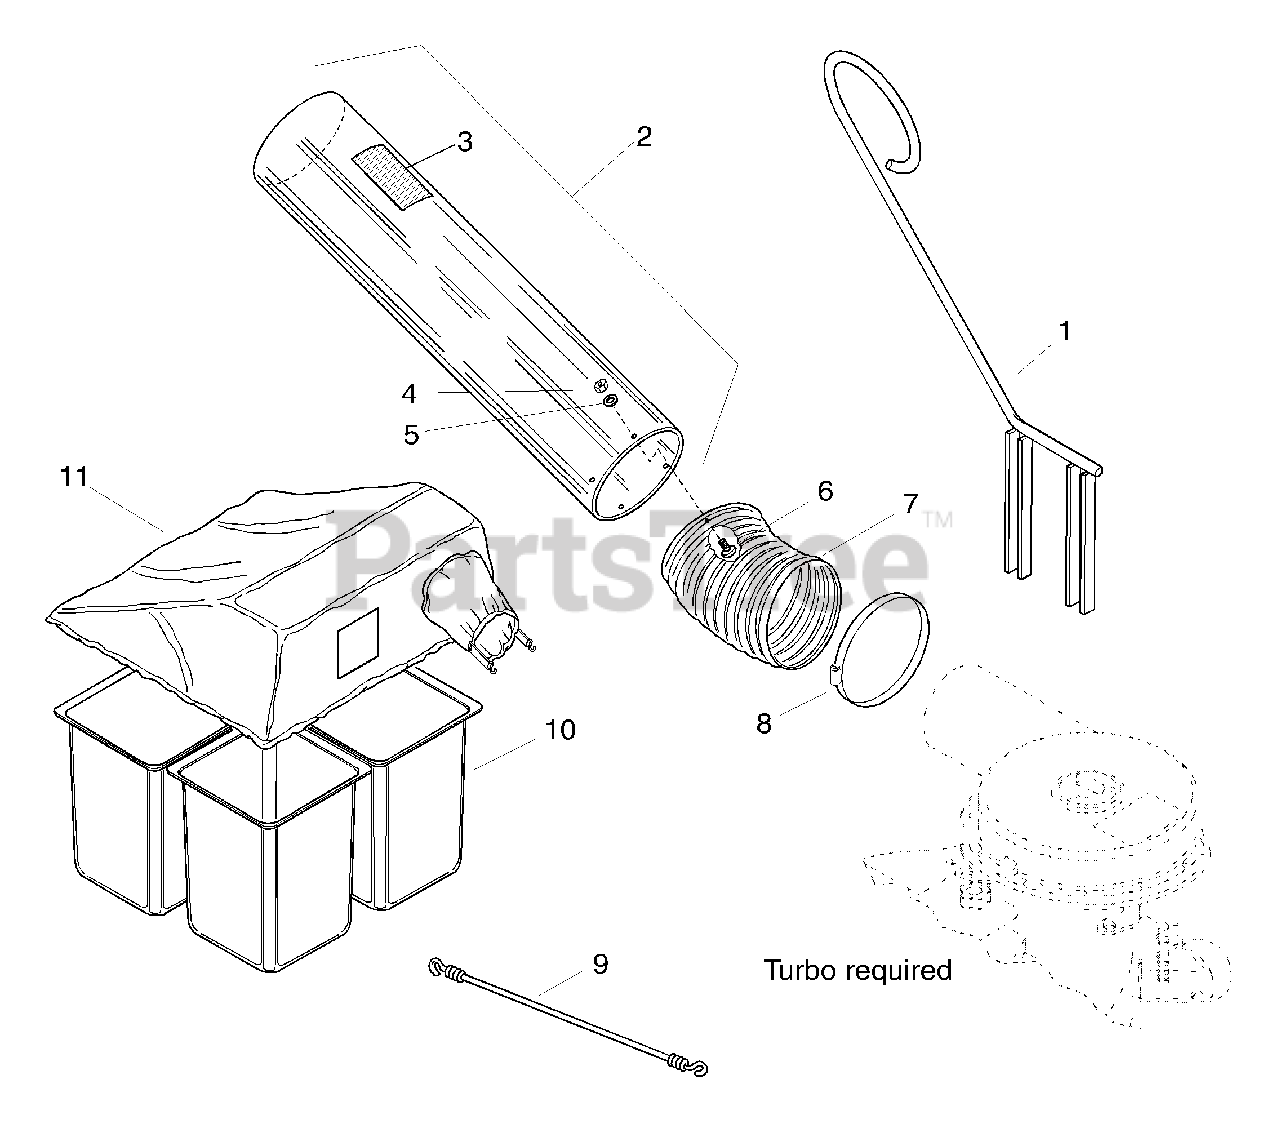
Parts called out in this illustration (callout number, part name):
2	TUBE & DECAL ASSEMBLY
3	DECAL, Cleaning Instructions
4	NUT, Hex & Washer Assembly, #10-32
5	WASHER, Plain, #10-32
6	SCREW, Truss Head Phillips, #10-32 X 1/2
7	HOSE, Vac Col, 6 X 12 Exhaust
8	CLAMP, Hose 6", Band Type
9	CORD, Shock 28," W/S-Hooks
11	HOOD, Quadbag W/Window
